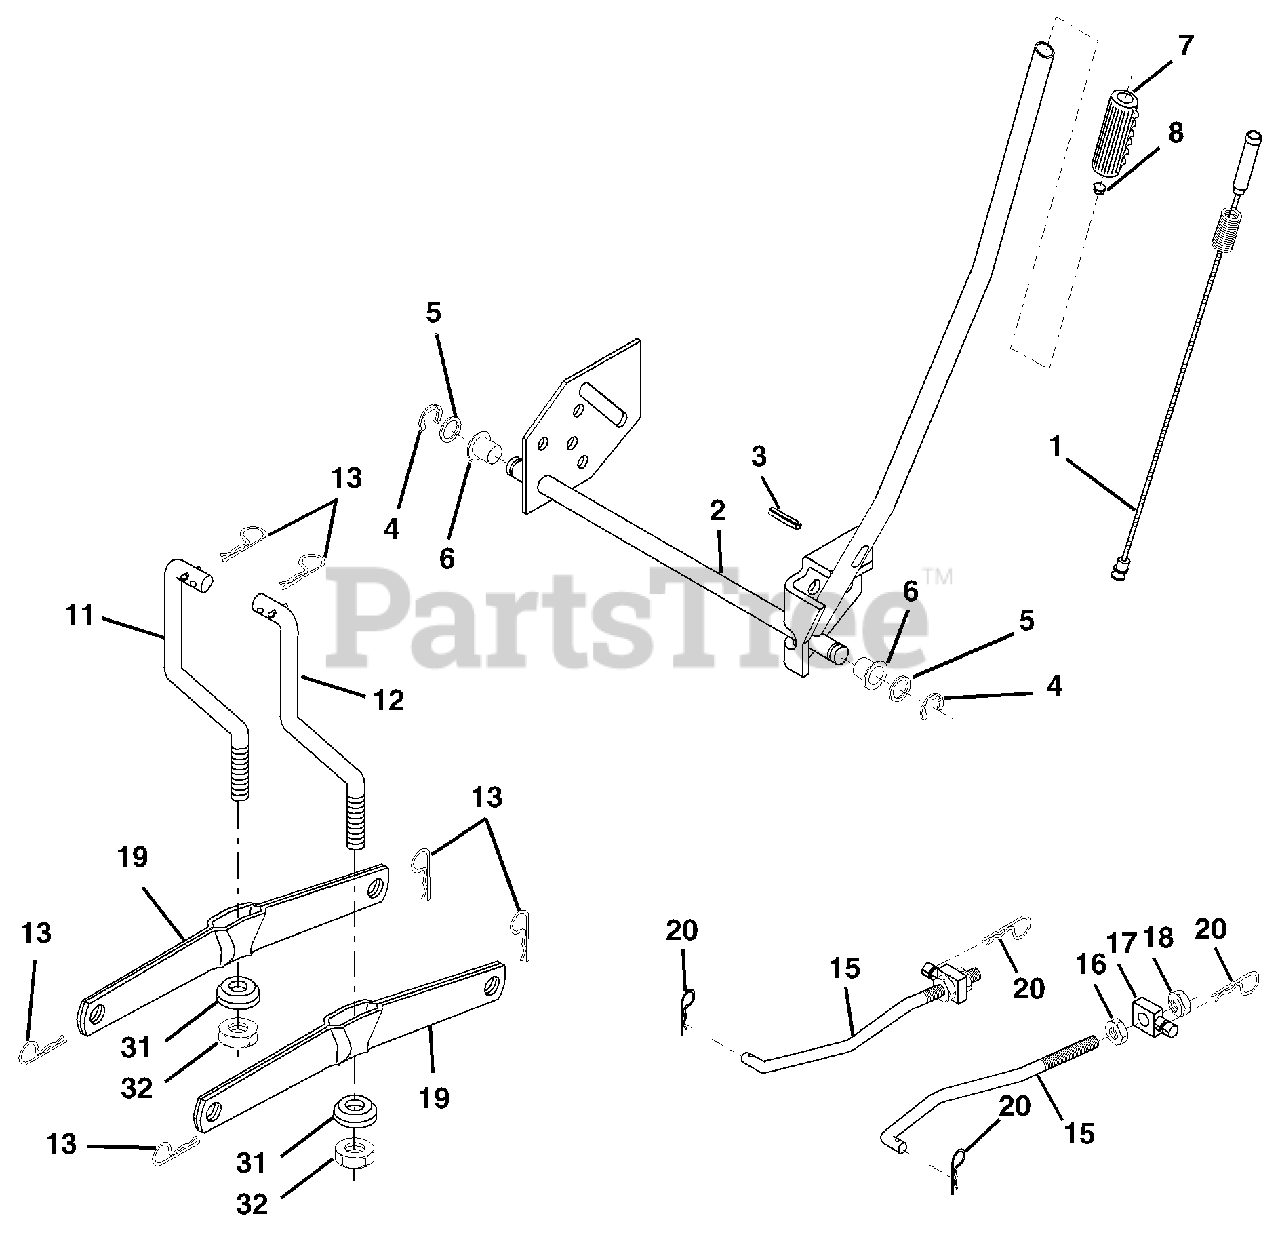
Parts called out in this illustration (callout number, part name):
1	Wire Asm Inner/Sprg W/plunger
2	Shaft Asm Lift RH w/Inf
3	Pin Groove 2"
4	E Ring #5133-62
5	Washer 21/32 x 1 x 21 Ga.
6	Bearing Nylon Blk 629 Id
7	Grip Handle
8	Button Plunger
11	Link Lift LH Fixed Length
12	Link Lift RH Fixed Length
13	Retainer Spring
15	Link Front
16	Nut Jam Hex 1/2-13 unc
17	Trunnion
18	Nut Lock W/Wsh 1/2-13 unc
19	Arm Suspension Rear
20	Retainer Spring
31	Bearing Pvt Lift
32	Nut Crownlock 3/8 - 24
